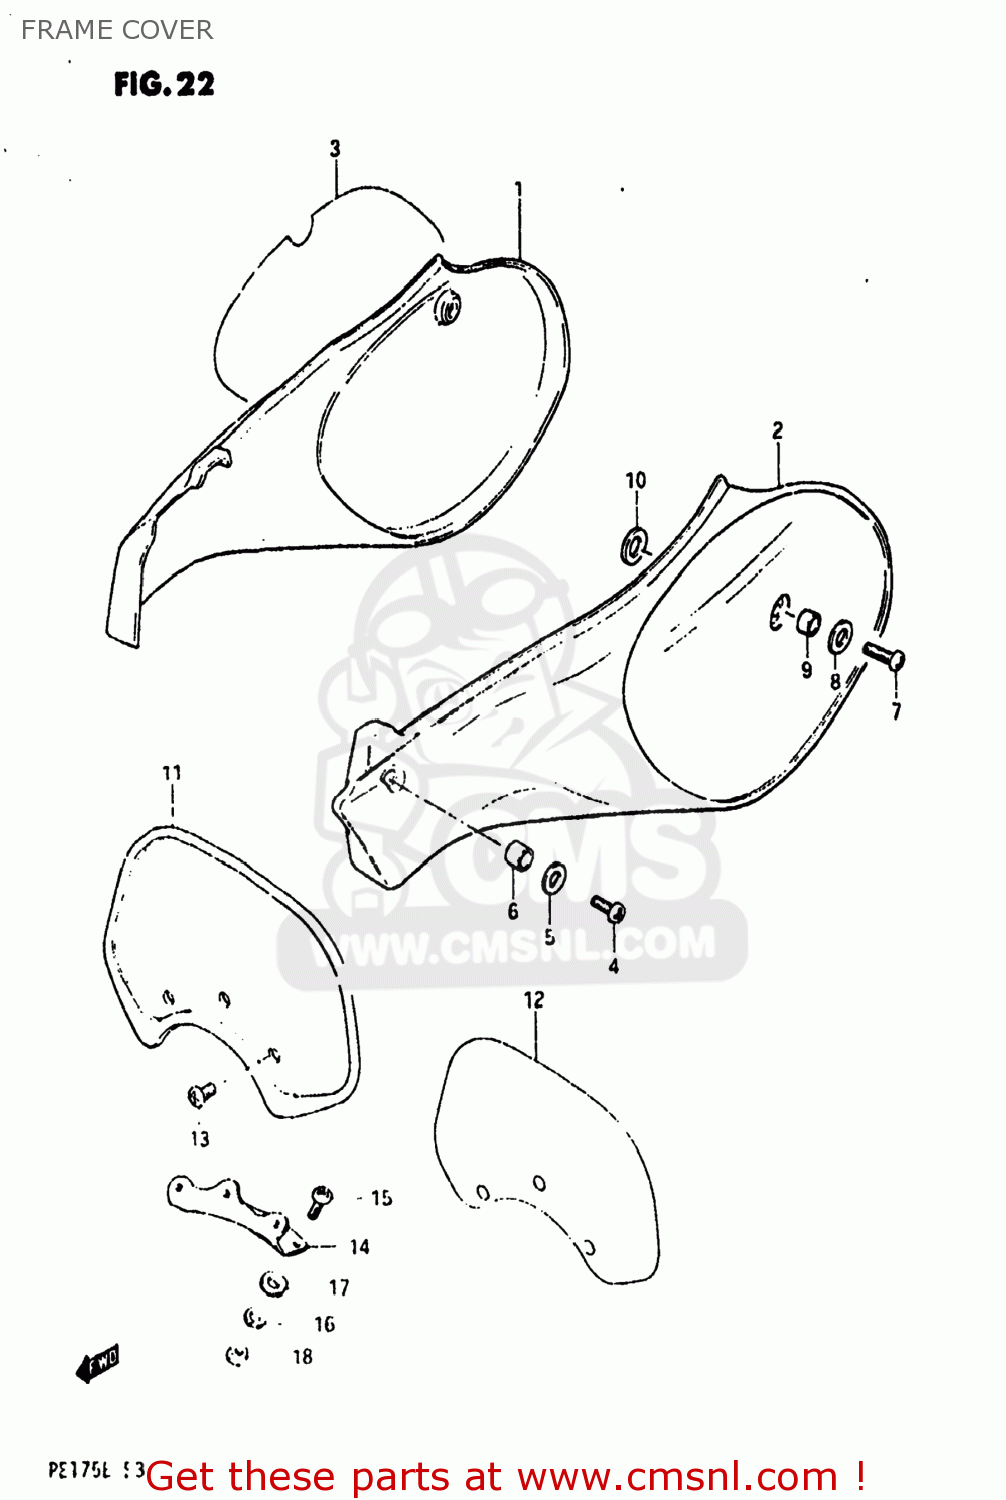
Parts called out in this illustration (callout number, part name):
1	COVER,FRAME,RIGHT
2	COVER,FRAME,LEFT
3	EMBLEM,NBR PLATE
4	SCREW
5	WASHER
6	SPACER (6.1X8X12)
7	SCREW
8	WASHER
9	SPACER
10	GASKET
11	PLATE,FRONT NUMBER
12	EMBLEM,FRONT NUMBER PLATE
13	SCREW
14	BRACKET FR NUM PLATE
15	SCREW
16	LOCK WASHER
17	WASHER
18	NUT
